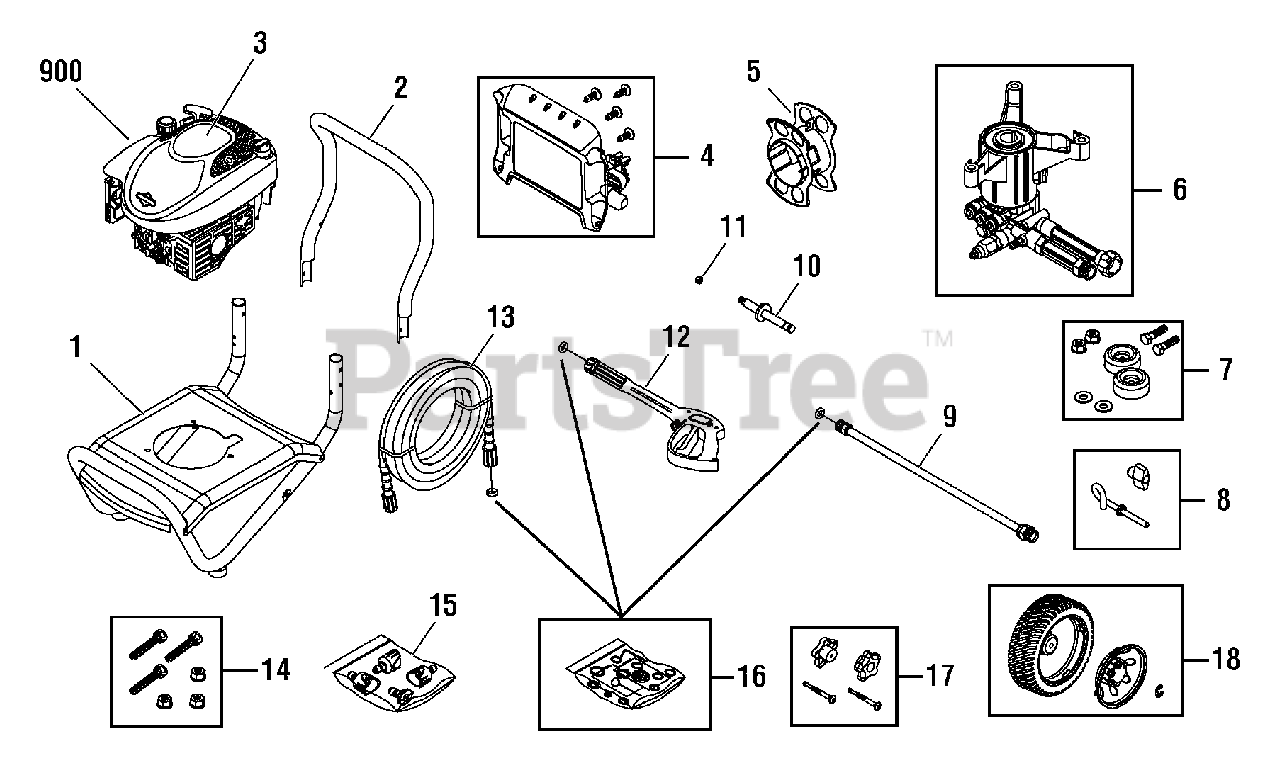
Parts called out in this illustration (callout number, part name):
6	PUMP
7	MOUNT, Vibration
9	EXTENSION, QC
10	AXLE
11	NUT
12	GUN
14	KIT, Hardware, Pump Mounting
15	KIT, QC Nozzles
16	KIT, O-Rings
17	KIT, Hardware, Handle
18	KIT, Wheel
900	* ENGINE
